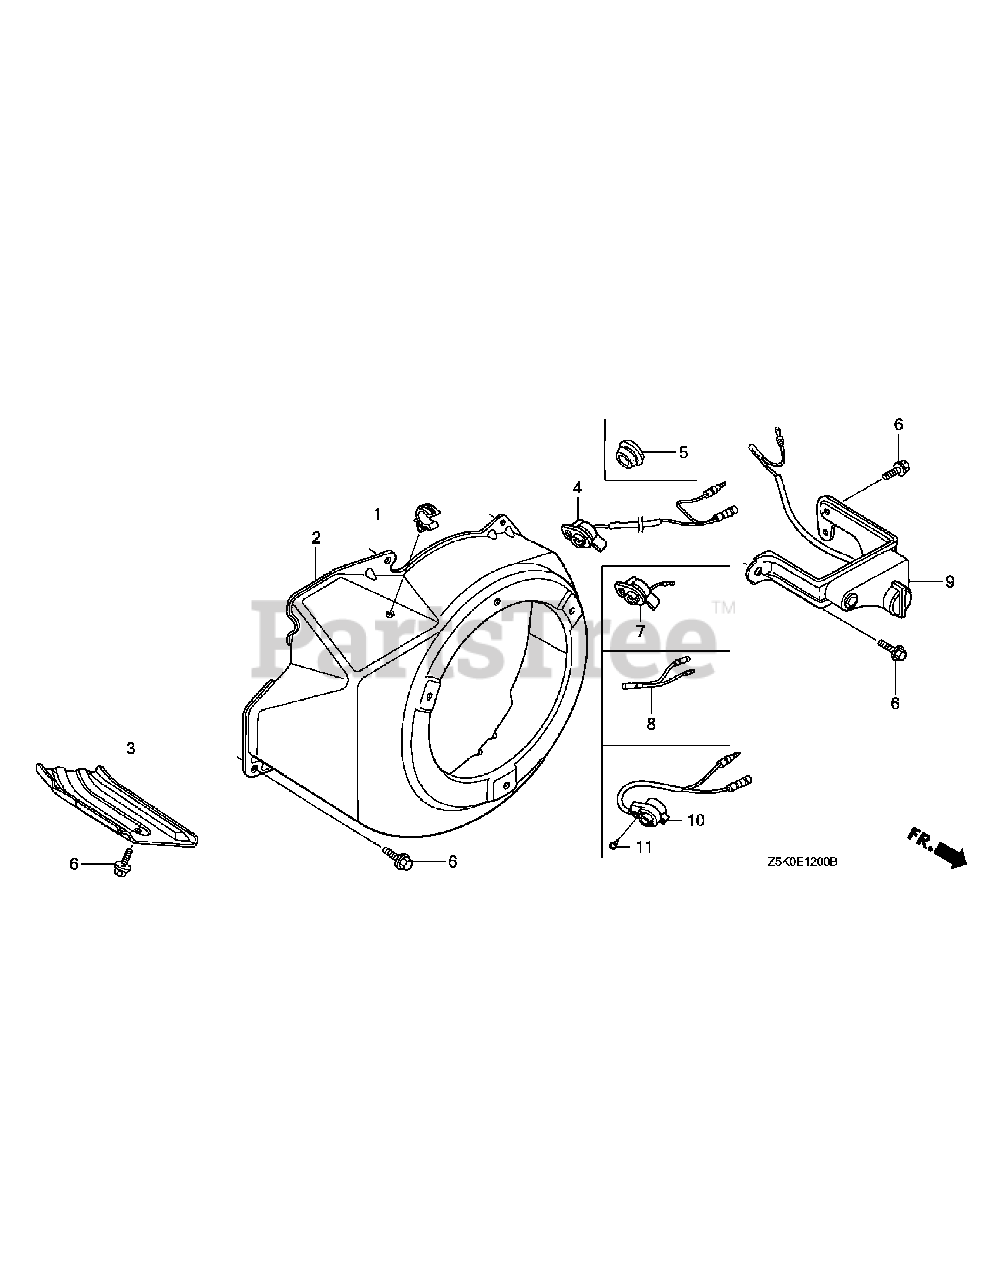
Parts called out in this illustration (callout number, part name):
1	Clip, Tube
2	Cover Comp., Fan
4	Switch Assy., Engine Stop
5	Grommet, Drain Hole
6	Bolt, Flange, 6X12(Ct200)
7	Switch Assy., Engine Stop
8	Sub Harness
9	Switch Assy., Engine Stop (Sdmo)
10	Switch Assy., Engine Stop
11	Screw, Tapping, 3X6(Po)
